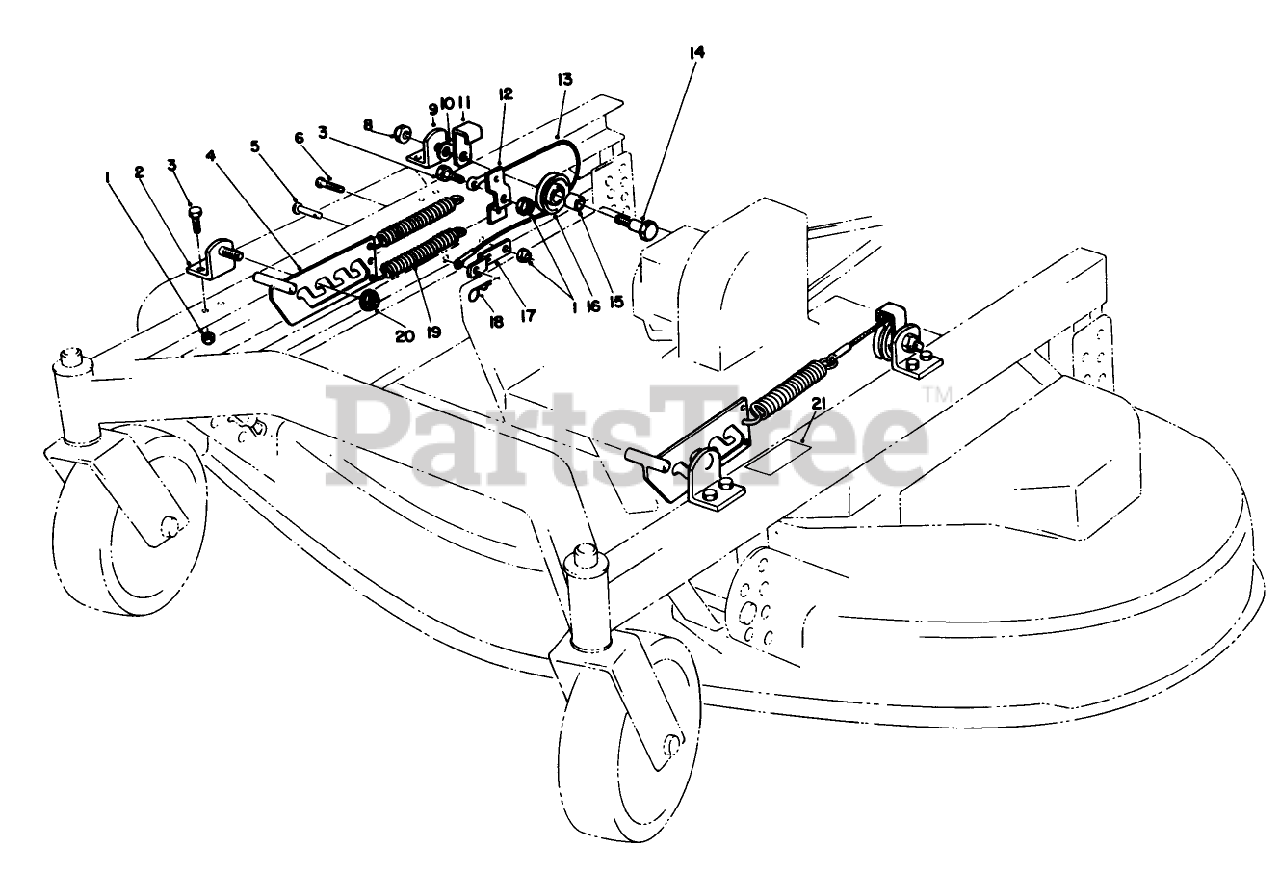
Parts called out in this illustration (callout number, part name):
1	NUT-LOCK, NI
2	Bracket-Control
3	SCREW-HH
4	Control-Tension
6	1/4-20 X 5/8 RD HD SC
8	NUT-LOCK, NI
9	Bracket-Pulley
10	WASHER-PLAIN
11	CABLE RETAINER
12	SPRING BRACKET
13	CABLE
14	BOLT-SHOULDER
15	BUSHING
16	Pulley Assembly (Incl. Ref. #15)
17	Bracket-Anchor
18	PIN-COTTER
19	EXTENSION SPRING
20	NUT-HF
21	DECAL-WARNING
